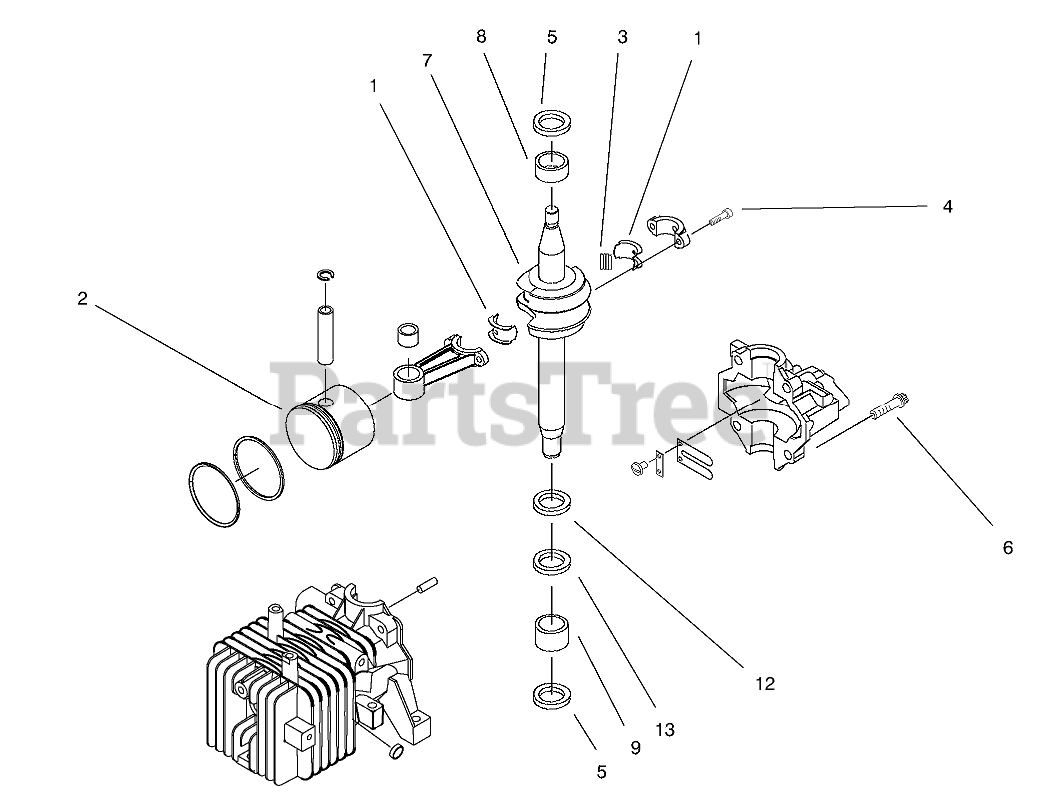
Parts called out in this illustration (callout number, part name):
1	LINER ASM
2	PISTON&CONN.ROD V
3	Roller Strip
4	SCREW-HSH
5	SEAL-OIL
6	SCREW-HWH V
7	CRANKSHAFT V
8	BEARING V
9	BEARING V
12	BEARING-THRUST
13	WASHER-THRUST
